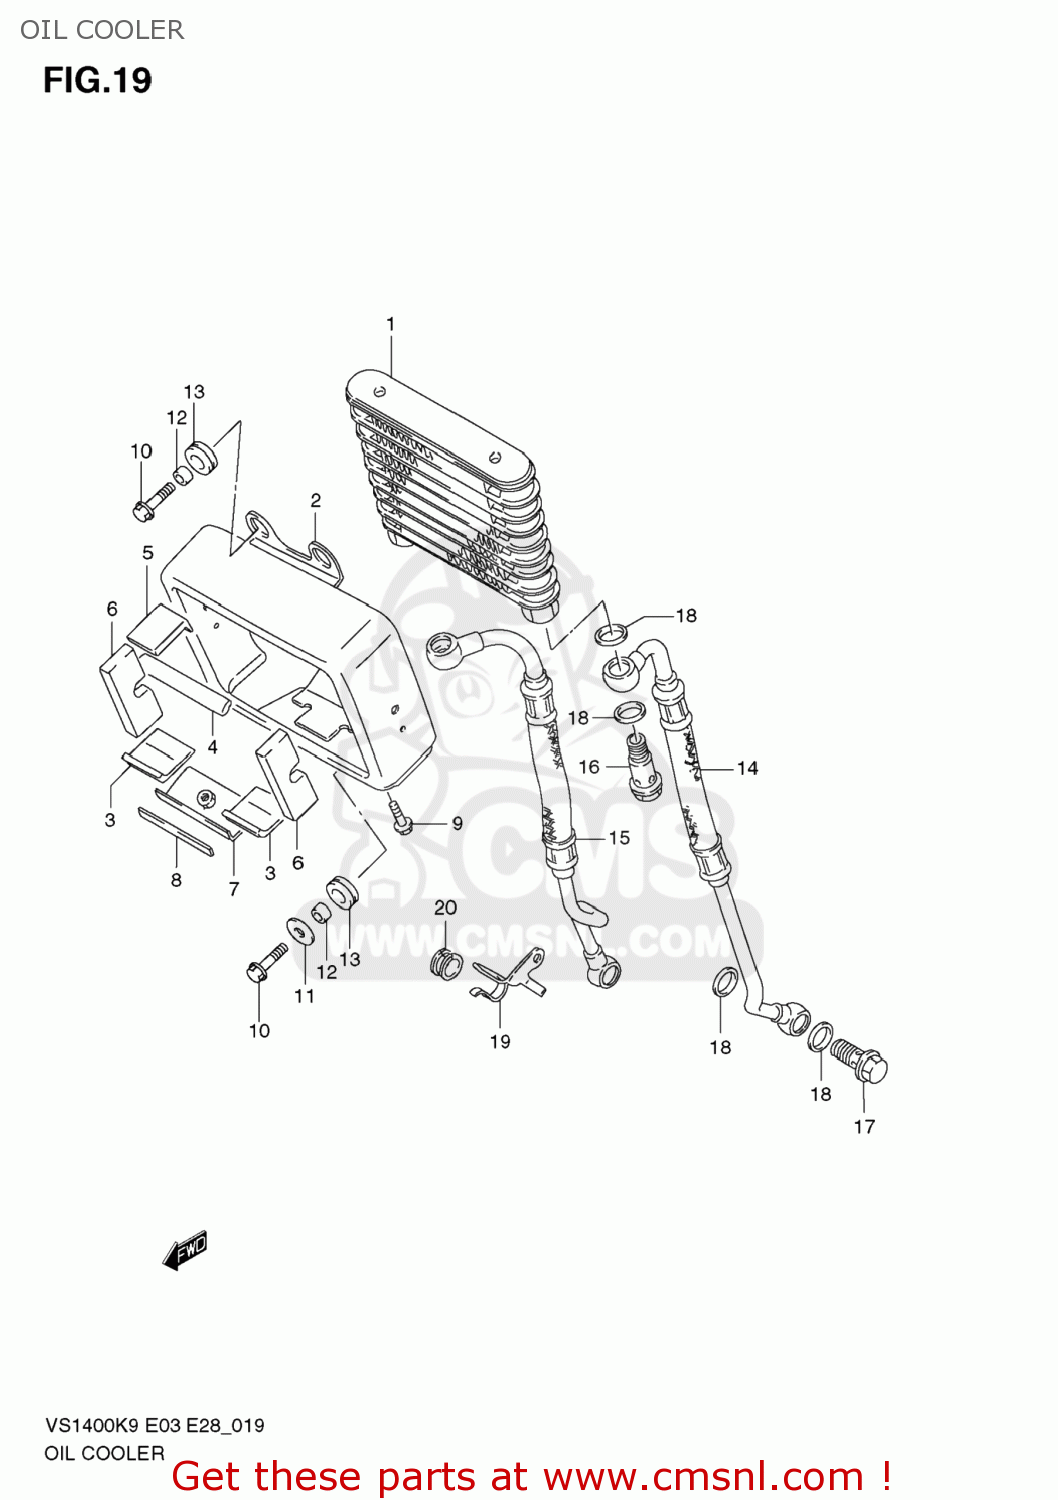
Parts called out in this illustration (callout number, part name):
1	COOLER ASSY,OIL
2	COVER,OIL COOLER
3	CUSHION,COOLER COVER LWR
4	CUSHION,CLLOER COVER UPR NO2
5	CUSHION,COOLER COVER UPR NO1
6	CUSHION,COOLER COVER SIDE
7	BRACKET,OIL COOLER
8	CUSHION,OIL COOLER BRACKET
9	BOLT
10	BOLT
11	WASHER(6.5X20X1.6)
12	SPACER(6.5X10X10)
13	CUSHION
14	HOSE,OIL COOLER,L
15	HOSE,OIL COOLER,R
16	BOLT UNION
17	BOLT UNION
18	GASKET(14X20X1.5) (NAS)
19	CLAMP,OIL COOLER HOSE,R
20	CUSHION
